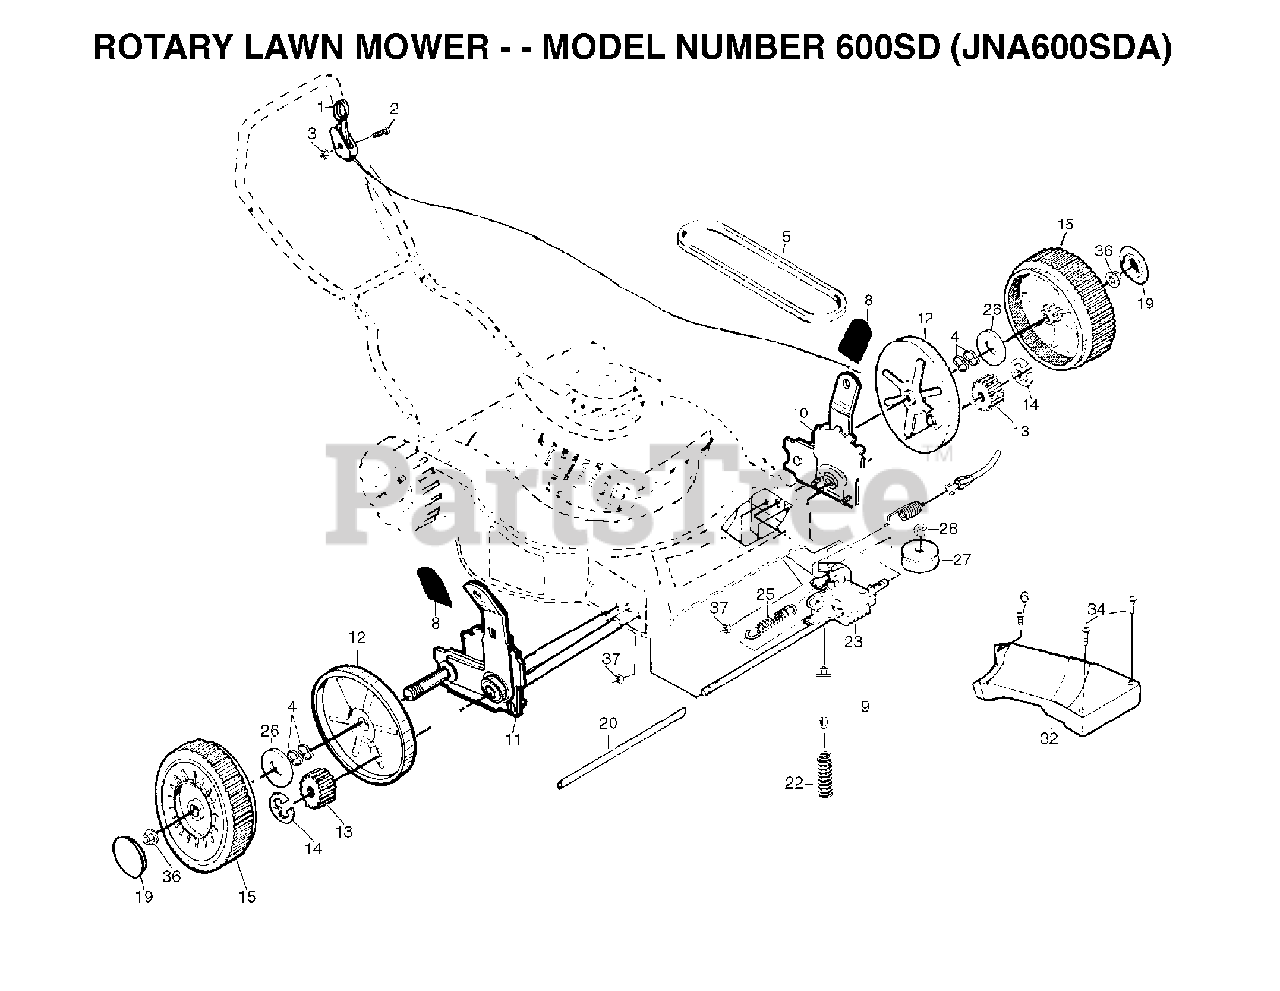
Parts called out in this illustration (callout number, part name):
1	SCREW
2	BRACKET
6	GEAR CASE
8	WORM SHAFT
9	DRIVE SHAFT, 20-5/8"
10	THRUST WASHER
11	YOKE CLUTCH
14	GEAR.HELICAL
15	CLUTCH JAW
16	GREASE
18	HI PRO KEY
19	BRACKET SPRING
